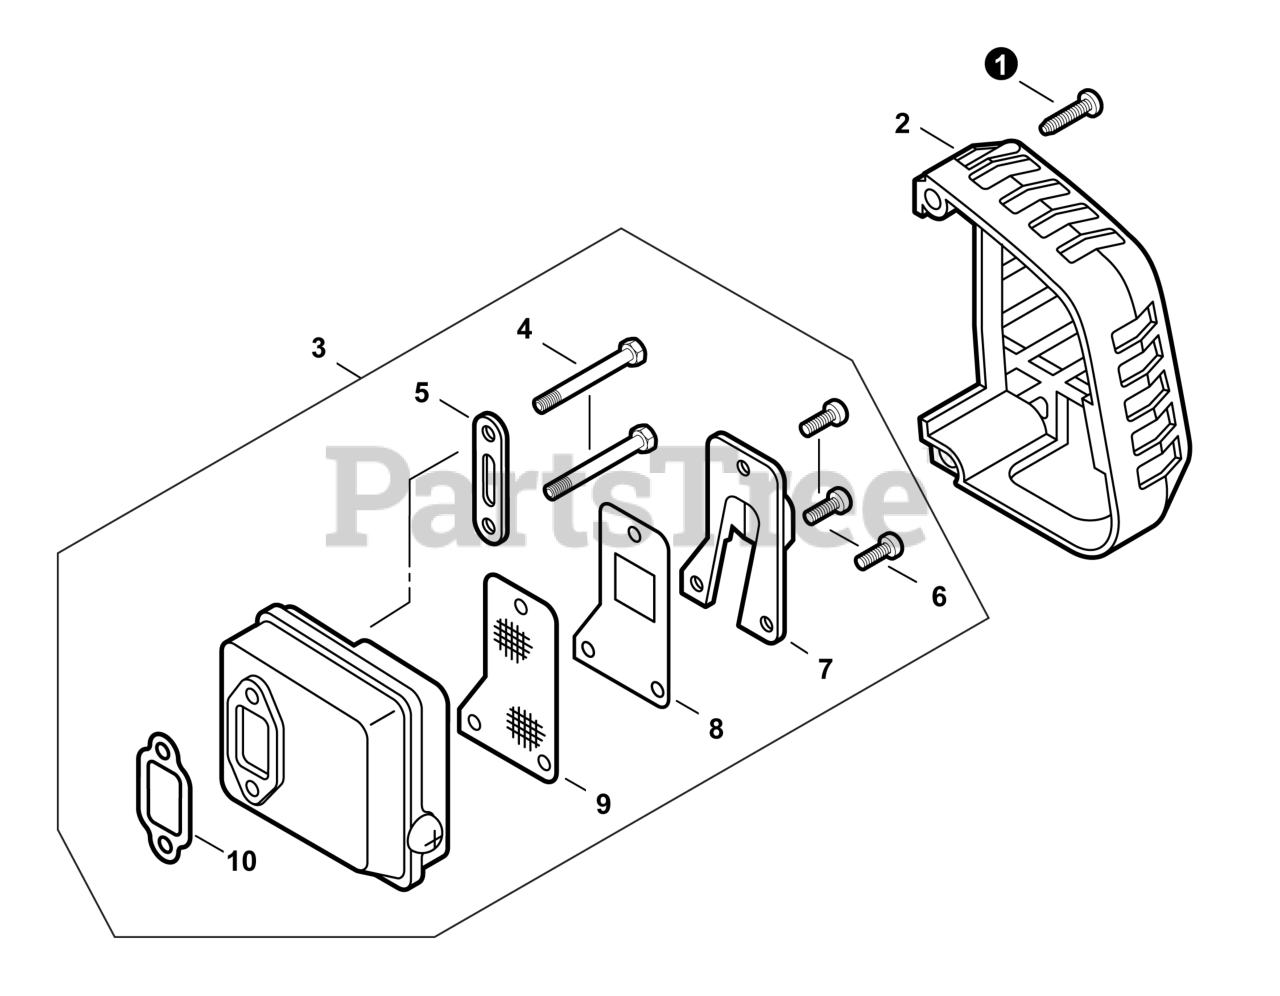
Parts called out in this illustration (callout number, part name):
1	SCREW, TAPPING 5x20
2	COVER, MUFFLER
3	MUFFLER ASSY
4	BOLT, FLANGE HSH 5x45
5	PLATE, EYE
6	SCREW 4x10
7	COVER, MUFFLER
8	GASKET, EXHAUST
9	SCREEN, SPARK ARRESTER
10	GASKET, MUFFLER
